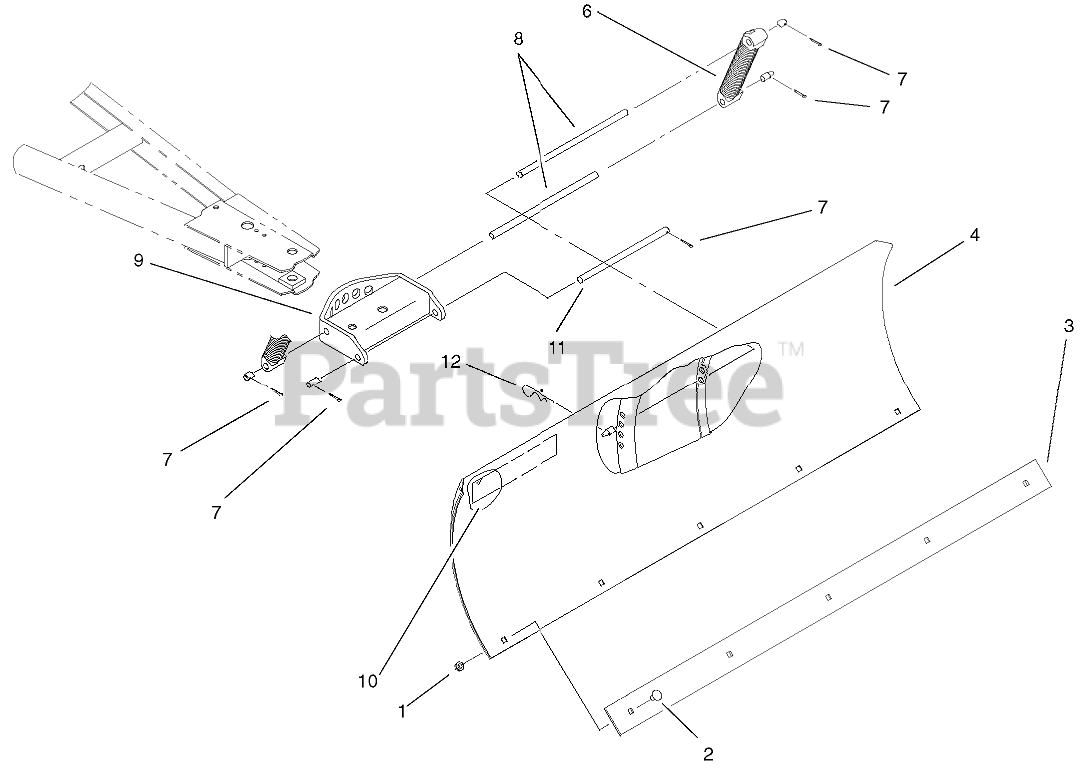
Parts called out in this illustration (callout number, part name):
1	NUT-LOCK, NI
2	SCREW-CARR
3	PLATE - BLADE EDGE
4	BLADE ASM
6	LUG / SPRING ASM
7	PIN-COTTER
8	ROD-PIVOT, BLADE
9	QUADRANT
10	DECAL-ATTACHMENT
11	ROD-LOWER
12	PIN-HAIR
